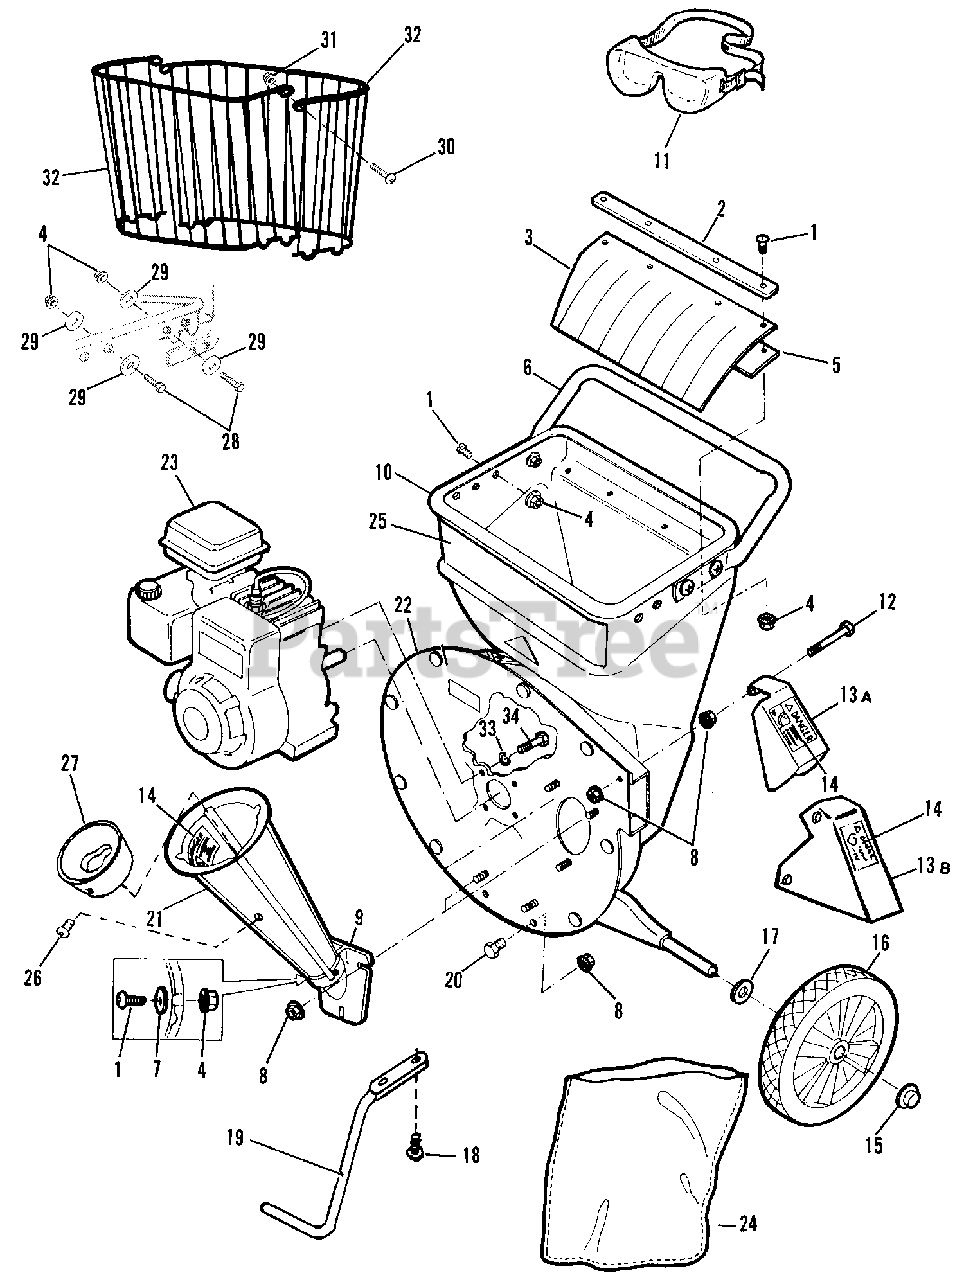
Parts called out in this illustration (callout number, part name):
1	SCREW, Hex, Button Hd., 1/4-20 x 3/4 (Qty.10 used on European models)
2	RETAINING STRIP, Hopper Guard
3	GUARD, Hopper
4	NUT, Flange, 2-Way Lock, 1/4-20 (Qty.10 used on European models)
5	SUPPORT, Hopper Guard
6	HANDLE
7	WASHER, Plain, 17/64 x 518 x 3164
8	NUT, Whiz, 5/16-18
9	CASTING, Chipper Cone, 3"
10	HOPPER, Red
11	SAFETY GOGGLES
12	CAPSCREW, Hex, 5/16-18 x 3-1/4, Gr.5
13A	DEFLECTOR
13B	DEFLECTOR, Fi x ed (European model only)
14	DECAL, Danger
15	PUSH NUT, 1/2
16	WHEEL & TIRE ASSY., 1-3/4 x 12 (5/14 Only)
16	WHEEL & TIRE ASSY., 2-1/4 x 12 (8/14 Only)
17	WASHER, Plain, 17/32Plain, 17/32 x 1-1/4 x 5/64
18	SCREW, Taptite, 3/8 16 x 1-1/4
19	ROD LEG
20	CAPSCREW, Hex, 5/16-18 x 5/8
21	CONE, Chipper, Red
22	ENGINE PLATE ASSY.
23	ENGINE, 5 HP, Briggs & Stratton ENGINE, 8 HP, Briggs & Strat
24	COLLECTION BAG, 24" x 36"
25	DECAL, Snapper
26	SCREW, Round. Hd., Phillips, 1/4-20 x 1/2 (European model only)
27	INSERT, Cone (European model only)
28	CAPSCREW, Hex, 1/4-20 x 1, Gr. 5 (European model only)
29	WASHER, Plain, 1/4 x 1-1/4 x 5/64 (European model only)
30	SCREW, Truss Hd., 5/16-18 x 3/4 (European model only)
31	NUT, Flange, Whiz Lock, 5/16-18 (European model only)
32	HOPPER HALF, Upper (European model only)
33	Lockwasher, 5/16
34	CAPSCREW, Hex Hd., 5/16-24 x 3/4
